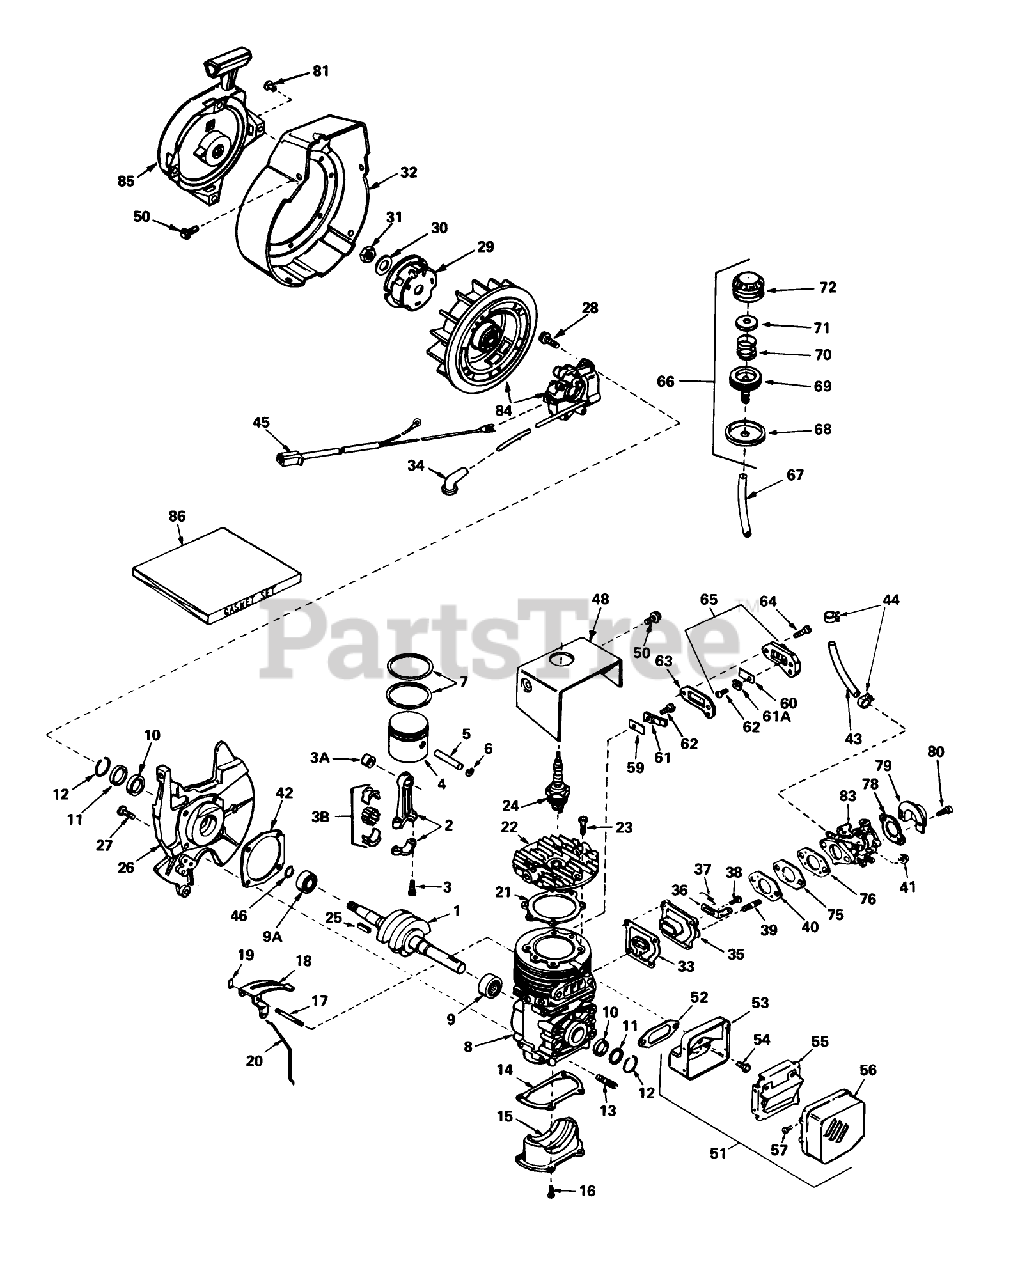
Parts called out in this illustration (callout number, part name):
1	Crankshaft
2	Rod Assembly, Connecting (Incl. #3, 3A 3B)
3	Bolt-Rod, Connecting
3A	Bearing-Cartridge
3B	Bearing Liner Set Needle
4	Piston
5	Pin, Piston
6	Ring-Retaning
7	Ring Set
9	Bearing-Cartridge
9A	Bearing-Ball
10	Seal, Crankshaft
11	Retainer, Crankshaft Seal
12	Spring, Crankshaft Seal Retainer
14	Gasket, Cover
15	Plate, Cover
16	Screw (T-25, 10-24 x 1/2)
17	Shaft, Air Vane
18	Vane Assy., Air
19	Clip,Air Vane
20	Link, Governor
21	Gasket, Head
23	Screw (T-30, 1/4-20 x 3/4)
24	Plug, Spark (RJ-13Y or equivalent)
25	Key, Flywheel
26	Base Assy., Housing (Incl. Nos. 29, 30 31)
27	Screw
28	Screw, Hex Washer Hd.
29	Starter Cup
30	Washer-Spring
31	Nut-Flywheel
32	Housing, Blower
33	Gasket, Port
34	Cover-Spark Plug
35	Adapter, Cover
36	Lever, Adjusting
37	Spring, Governor
38	Screw
40	Gasket, Carburetor 1/8" thick)
41	Locknut
42	Gasket, Shroud Base
43	Line-Fuel (8.62)
44	Clamp-Line, Fuel
45	Harness, Wire
46	Ring, Retaining
48	Shroud, Cylinder
50	Screw-Hex, Hd.
51	Muffler Assembly (Incl. #53-57)
52	Gasket-Muffler
53	Base-Muffler
54	Screw
55	Baffle, Muffler
56	Cover, Muffler
57	Screw
59	Reed, Compression Release
60	Reed, Compression Release
61	Plate, Reed Hold Down
61A	Plate, Reed Hold Down
62	Screw
63	Gasket, Compression Release
64	Screw
65	Cover Assy., Compression release (Incl. Nos. 60, 61A 62)
66	Primer Assy. (Incl. Nos. 67 thru 72)
67	Line, Primer
68	Retainer, Primer Bulb
69	Body, Primer
70	Spring, Primer Bulb
71	Washer, Primer Bulb
72	Bulb, Primer
75	Spacer
76	Gasket, Carburetor (1/16"thick)
78	Gasket
79	Baffle-Carburetor
80	Screw
81	Rivet, Pop (3/16" dia.) (Can be purchased locally)
83	Carburetor (Incl. No. 76)
84	Magneto
85	Starter-Rewind
86	Gasket Set (Incl. items marked *)
